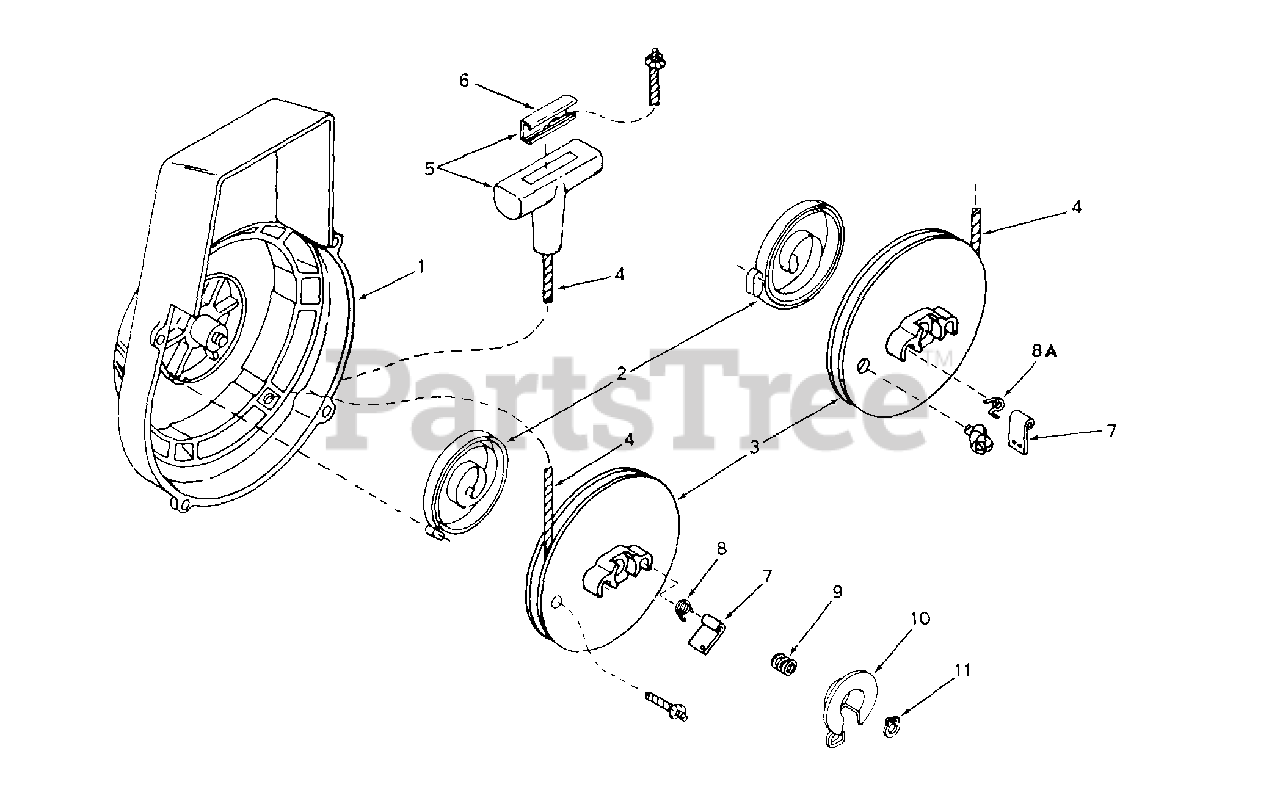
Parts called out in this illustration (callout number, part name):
1	Housing Assy., Shroud & Starter
2	Spring, Rewind
3	Pulley, Starter rope (Incl. 8)
4	Rope Starter Length 61" & 11/64" Dia.
5	Handle Assy., Starter rope (Incl. 6)
6	Insert, Handle
7	Dog, Starter
8A	Return Spring, Left hand wound
9	Spring, Brake
11	"E" Ring Truarc
